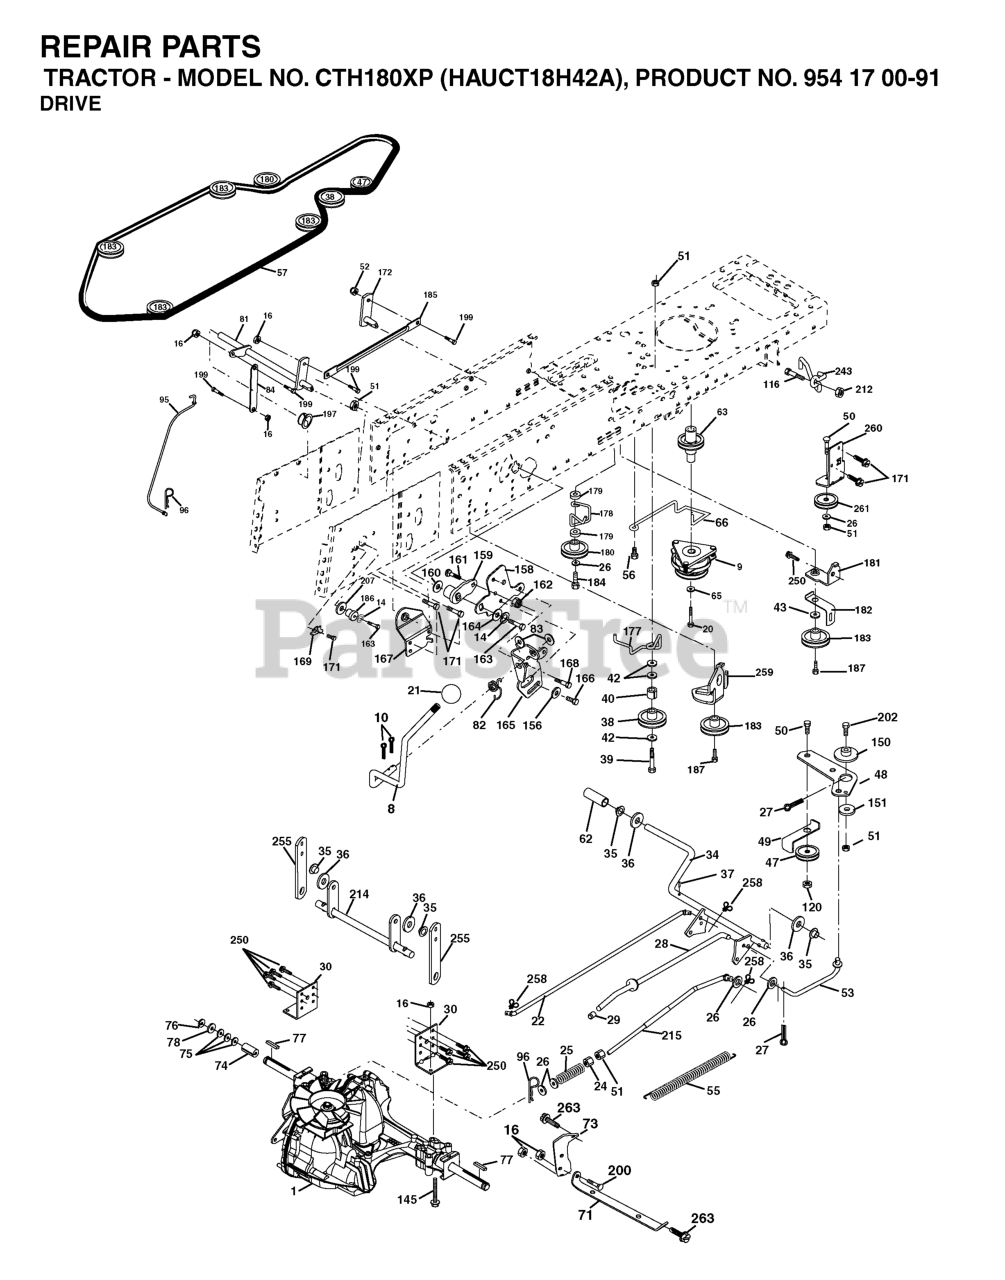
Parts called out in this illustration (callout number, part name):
8	ROD.SHIFT.FENDER.ADJ.LT.CRD
10	PIN COTTER
14	LOCKWASHER
16	NUT.71038.31-18.HEX.NYLOCK
20	BOLT
21	KNOB.DUCKHEAD.1/2
22	ROD
24	NUT
25	SPRING ROD LT
26	WASHER
27	COTTER PIN
28	ROD, PARKING BRAKE
29	PLUNGER CAP
30	BRKT, TRNSXLE MNT 20"
34	SHAFT, FOOT PEDAL
35	BEARING.NYLON
37	DRIVE PIN
38	PULLEY.FLAT
42	WASHER
47	IDLER PULLEY
48	BELLCRANK, CLUTCH
49	RETAIN BELT
50	BOLT.3/8-16X1.50
52	LOCKNUT
53	LINK, CLUTCH LT
55	SPRING, RETURN LT
56	SCREW.3/8-16
57	V-BELT 113"
62	COVER, PEDAL (1 2)
63	PULLEY.ENGINE.CVX.LT
65	LOCKWASHER
66	KEEPER BELT ENGINE
71	STRAP TORQUE LH HYDRO
73	STRAP TORQUE RH HYDRO
74	SPACER AXLE
77	SQUARE KEY
81	ASM.CROSS.SHAFT.REAR.CRD.0510
82	SHIFT SPRING
83	WASHER
84	LINK.PNT.TRANSAXLE.0510.CRD
95	LINK
96	RETAINER M
116	BOLT D
120	NUT LOCK FLG 3/8-16 UNC
145	BOLT HEX 5/16-18 GR 5
150	BUSHING.BELLCRANK.GRD.DR
151	WASHER 12/32X2X10GA
156	WASHER.SRRTD.5/16
158	BRACKET
159	HUB
160	Washer 29/32 x 1 - 1/4 x 16 Ga.
161	BOLT
162	NUT.CROWNLOCK.1/4
164	Washer 5/8 x .281 x 10 Ga.
165	RP BRACKET
167	BRACKET.SUPT.SHIFT.CRD
168	BOLT.SHOULDER.5/16-18X
169	PLATE.FASTENING.CROSS.SHAFT
172	LINK
180	PULLEY.FLAT.IDLER
181	BRACKET
182	BELT GUIDE
184	SCREW.HXWSH.3/8
185	LINK
186	HUB.TAPERED.ROUND.CRD
187	BOLT.5/16-18X1.25
197	NYLINER SNAP 5/8" ID
199	BOLT SHOULDER 5/16-18 UNC
207	WASHER NYL
212	NUT
214	LEVER
215	ROD
243	BRKT ASM MTNG
250	SCREW 3/8-16X3/4
255	SHAFT
258	CLIP RETAINER
259	BRACKET
261	FLAT IDLER PULLEY
263	SCREW, 3/8-16X3/4
